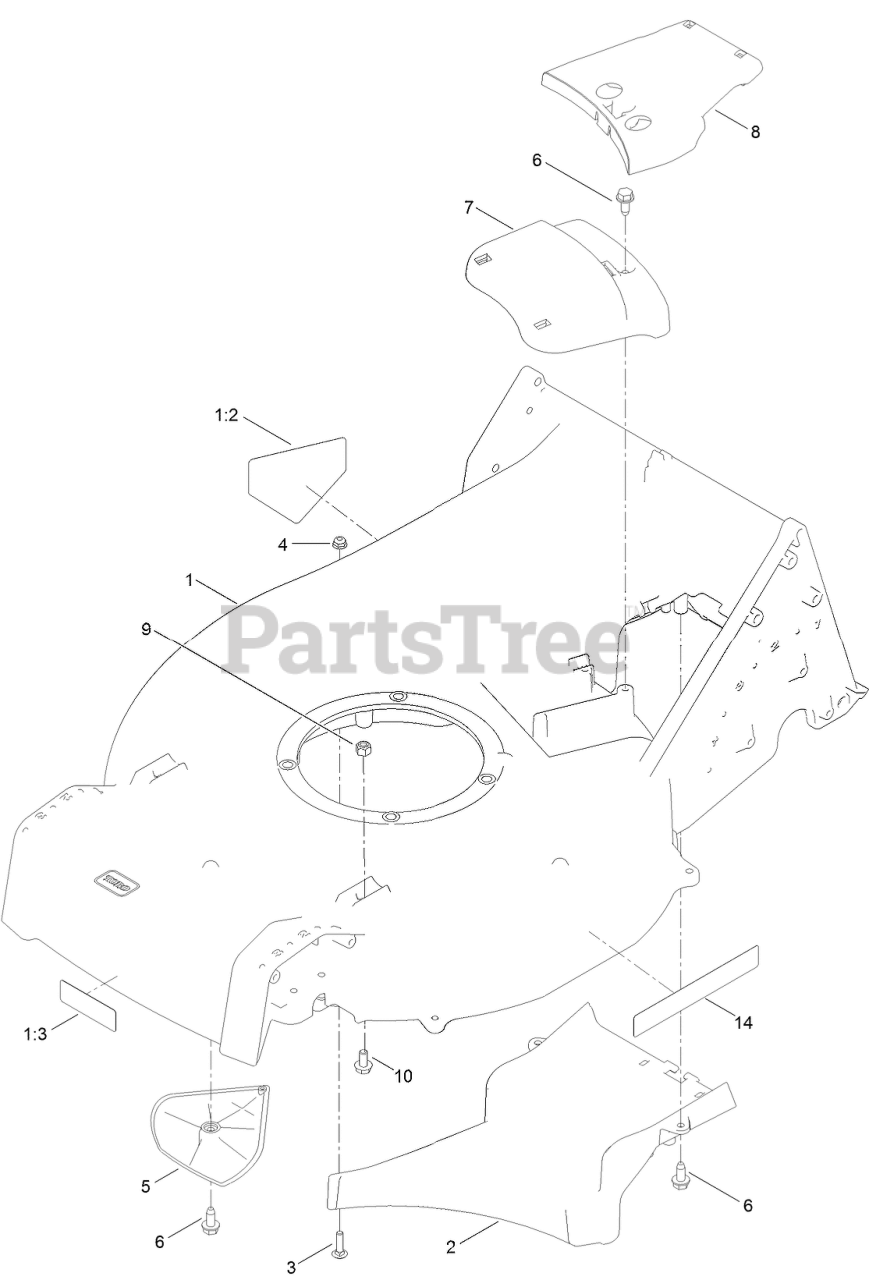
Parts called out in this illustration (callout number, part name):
1	HOUSING ASM
1:2	DECAL-DANGER
1:3	DECAL-WARNING, BLADE
2	FLOOR-CHUTE
3	SCREW-CARR
4	NUT-HF
5	KICKER
6	SCREW-HWHTF
7	COVER-BELT, FRONT
8	COVER-BELT, REAR
9	NUT-LOCK, NI
10	SCREW-HHF
14	DECAL-RECYCLER
